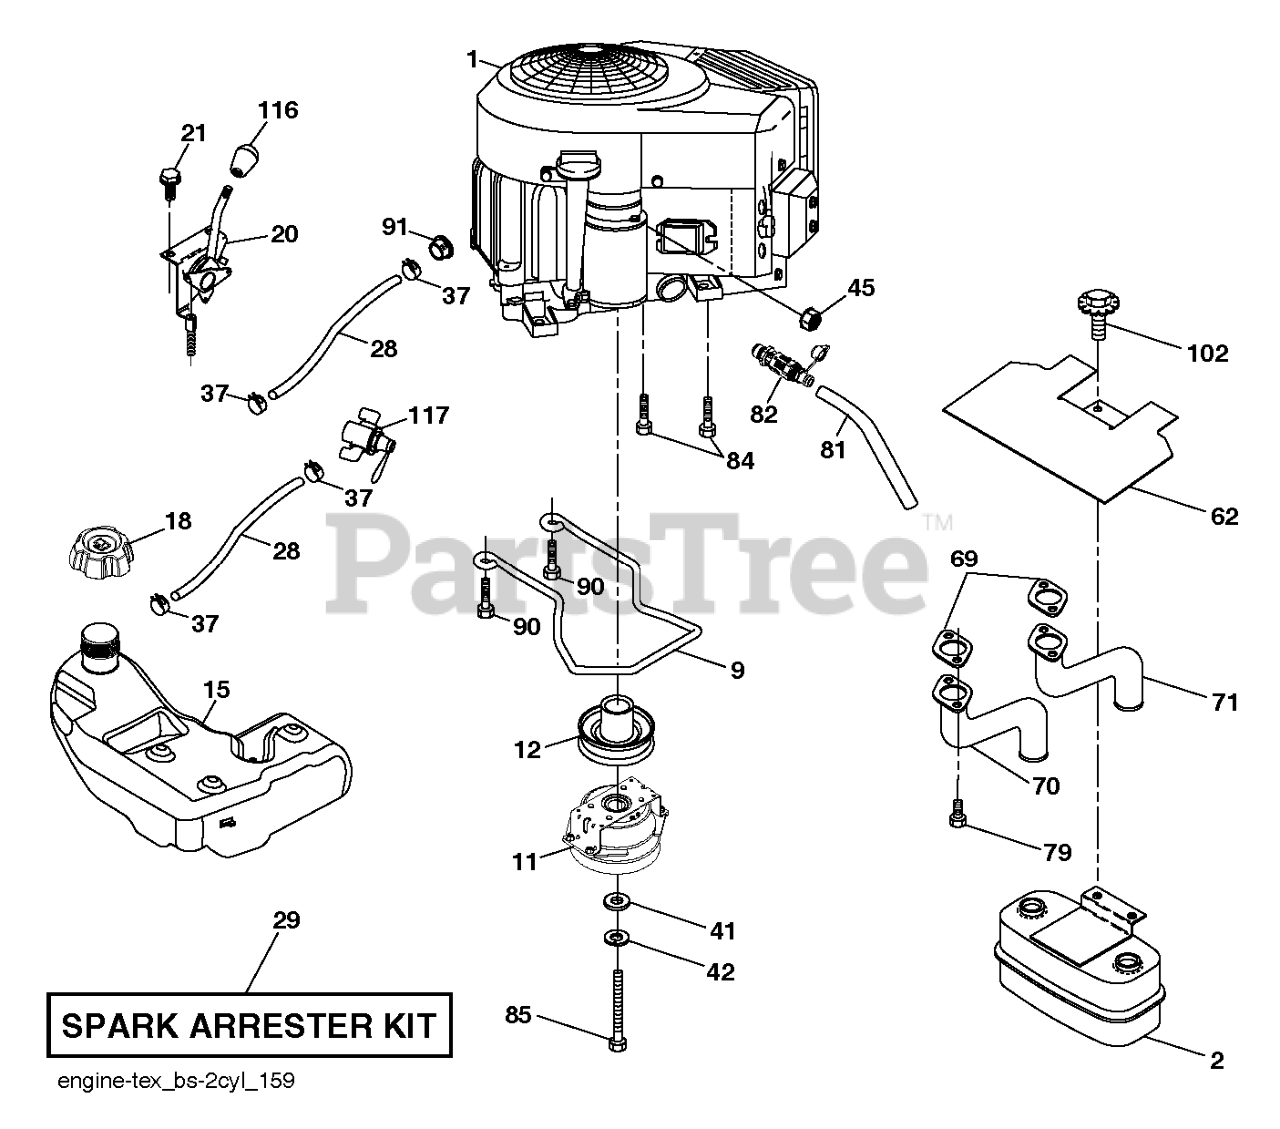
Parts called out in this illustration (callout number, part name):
2	MUFFLER.ASM.TWIN.MNTG.BRACKET
9	KEEPER.BELT.ENG.4.25"2.BLT.431
11	CLUTCH.OGURA.5.0PD.GT1.5A-EH01
12	PULLEY ENGINE
15	TANK.ASM.FUEL.4R.GAL.EPA.17
18	CAP ASSY FUEL 3" GRAY
18	FUEL CAP
20	THROTTLE.PRO.RSTART. 38
21	SCREW.#10 X 0.750.BOS
28	LINE.FUEL.64"REAR.EMIS
29	KIT.SPARK ARRESTOR 794945 B&S
37	HOSE CLAMP
42	WASHER 7/16 LOCK
45	NUT
62	SHIELD.HEAT.MUFFLER
69	GASKET.MUFFLER
70	EXHAUST.TUBE.LH.BS/TWIN
71	EXHAUST.TUBE.RH.B&S.TWIN.INTEK
79	SCREW.SOCKET.HEAD.5/16-18
81	TUBE, DRAIN OIL ASM.
82	VALUE.OIL.DRAIN
84	SCREW.3/8-16
85	BOLT.HEX.7/16-20X3.GR5.YELLOW
90	SCREW 3/8-16X1
91	BUSHING.1.375OD
102	SCREW
116	KNOB - SHIFT
117	VALVE FUEL RESERVE
